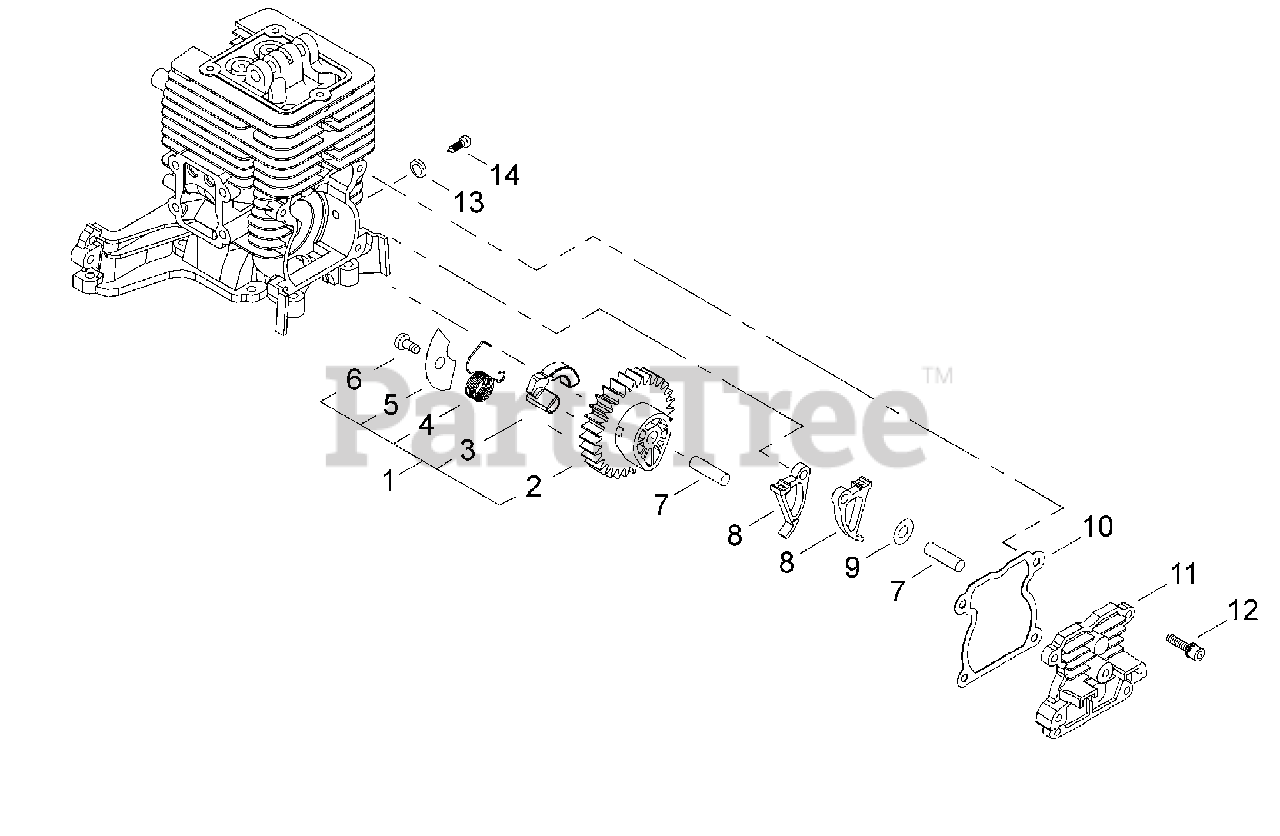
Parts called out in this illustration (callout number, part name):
1	CAM GEAR ASSY
2	GEAR, CAM
3	WEIGHT
4	SPRING
5	COVER, PLATE
6	SCREW - 4X6 -- TAPPING
7	PIN - LOCATING
8	FOLLOWER, CAM
9	WASHER - 5
10	GASKET
11	COVER, CAM GEAR
12	SCREW - 4X14
13	WASHER
14	SCREW - 5
